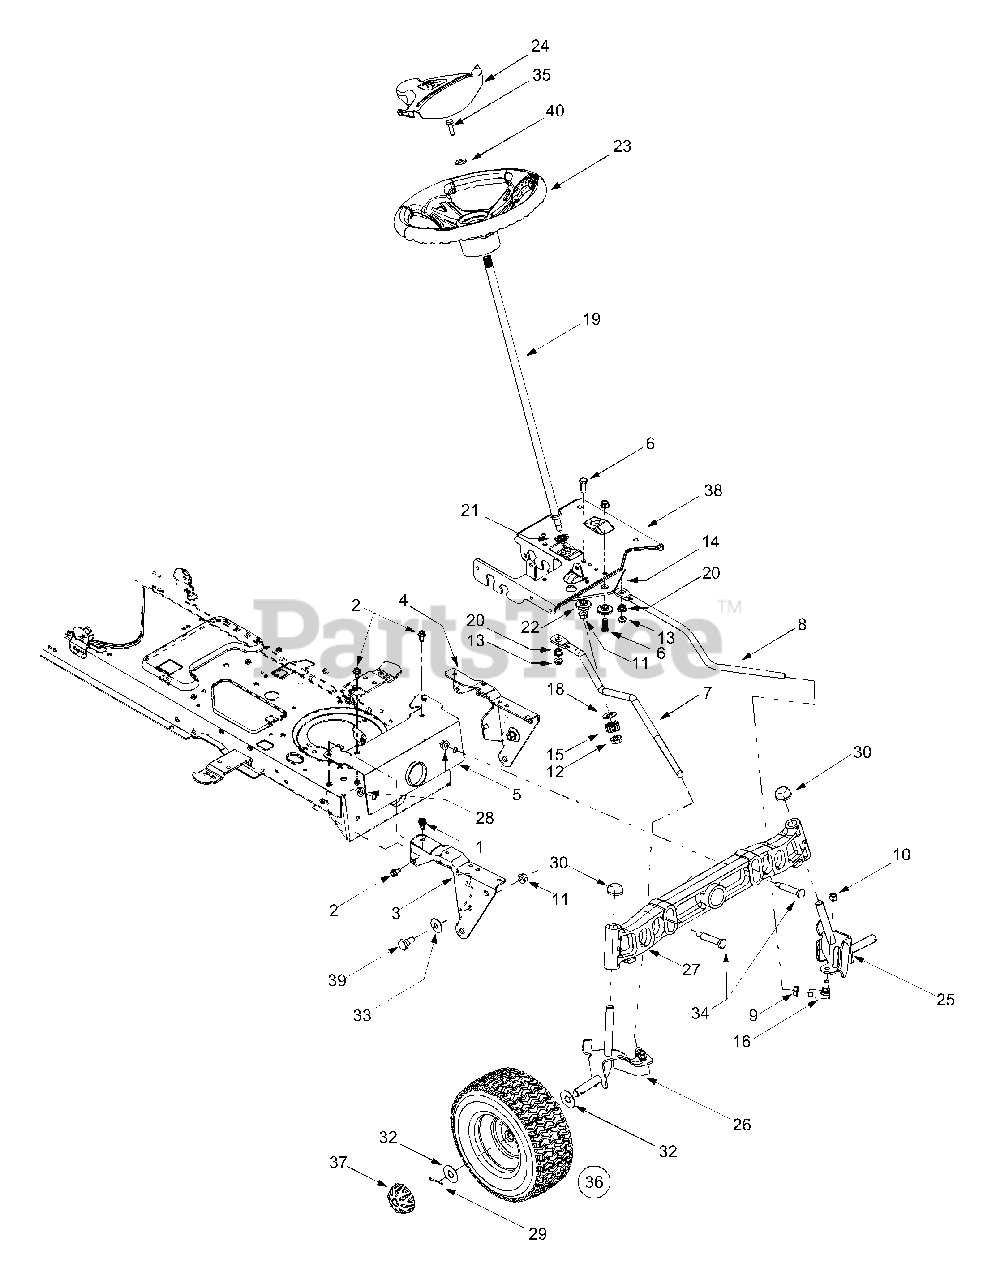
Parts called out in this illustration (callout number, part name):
1	Self-tapping Screw, 5/16-18 x .75
2	Self-tapping Screw, 16-18 x .625
6	Hex Cap Screw, 3/8-16 x 1
7	RH Drag Link
9	Jam Nut, 7/16-20
10	Center Lock Nut, 3/8-24
11	Flange Lock Nut, 3/8-16
12	Flange Lock Nut, 7/16-20
13	Flange Lock Nut, 5/16-18
14	Steering Gear, 11/90 Ratio
15	Steering Pinion Gear
16	Ball Joint, 7/16-20
18	Flat Washer, .51 x 1.12 x .06
19	Steering Shaft, .625 OD x 24.4
20	Plastic Bushing, .38 ID
21	Hex Flange Bearing, 5/8
22	Shoulder Spacer, .38 ID
23	Steering Wheel, Soft Grip, Three Spoke
24	Steering Wheel Cover
25	LH Axle Assembly, .750 Dia.
26	RH Axle Assembly, .750 Dia.
27	Cast Iron Pivot Bar w/ Fittings,.750
28	Flange Lock Nut, 3/8-16
30	Push Cap, .750
32	Flat Washer, .635 x 1.589 x .06
33	Bell Washer, .39 x 1.13 x .062
34	Shoulder Screw, .5 x 2.2, 3/8-16
35	Hex Bolt, 5/16-18 X 1
36	Wheel Assembly Compl 16 x 6.5 x 8
36	Tire Only, Square Shoulder
37	Hub Cap
38	Steering Support Bracket
39	Shoulder Screw, 3/8-16
40	Flat Washer, .406 x .875 x .105
